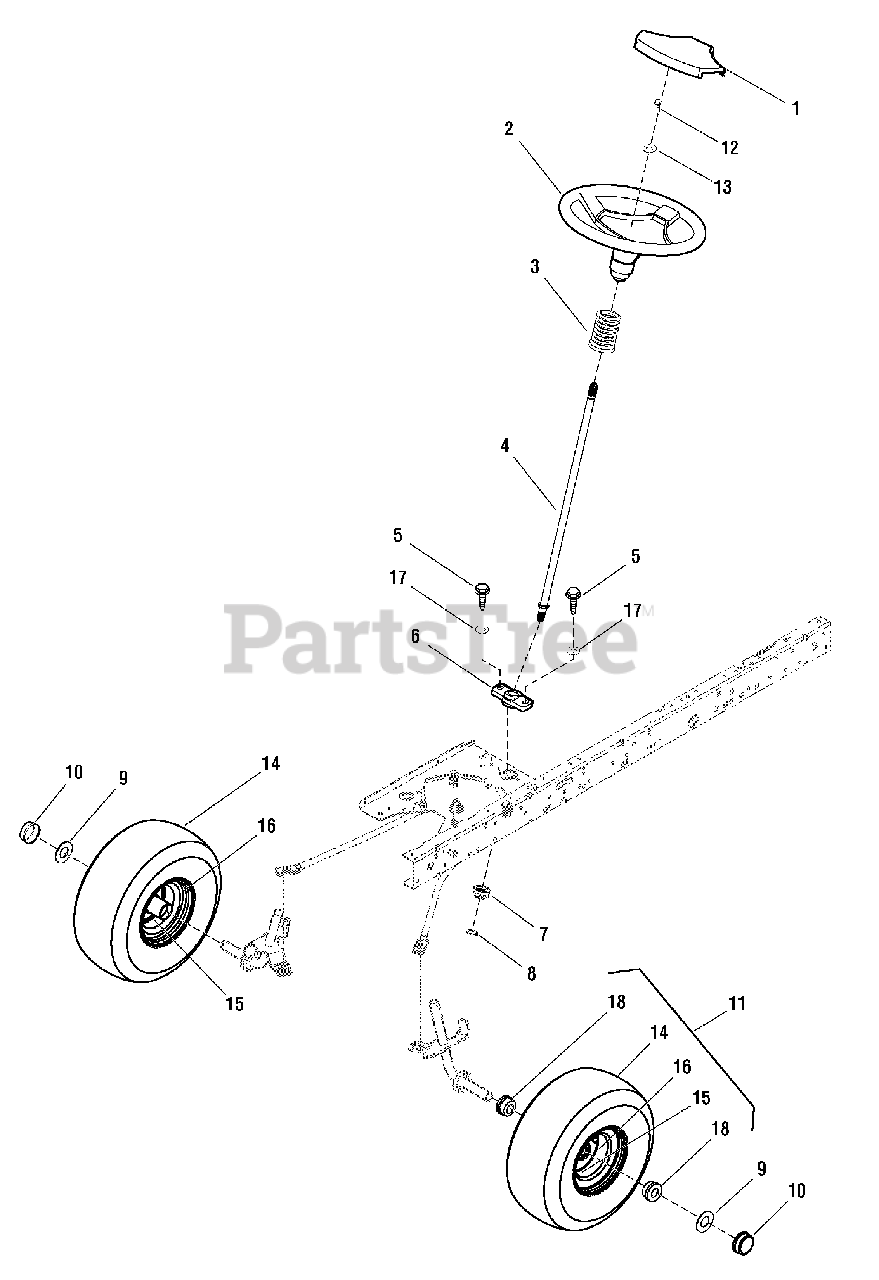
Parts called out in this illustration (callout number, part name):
1	COVER, Integra
2	STEERING WHEEL
3	BELLOWS
4	POST, Steering
5	SCREW, 5/16-18 x 7/8
6	BEARING, Lower
7	GEAR, Pinion
8	SNAP RING
9	WASHER, Flat
10	HUB CAP
11	WHEEL & TIRE ASSY, 15X6.0-6
12	SCREW, Thread Forming, 1/4-20 x 1
13	WASHER, FLAT, .344-1.20-.12
14	TIRE, 15 x 6 2 Ply K358
15	VALVE STEM, TR412
16	FITTING, Grease
17	WASHER, Flat, 3/4 x 1-1/4 x 16GA
18	BUSHING, 3/4" ID x 1.38" OD Hardened (per wheel)
